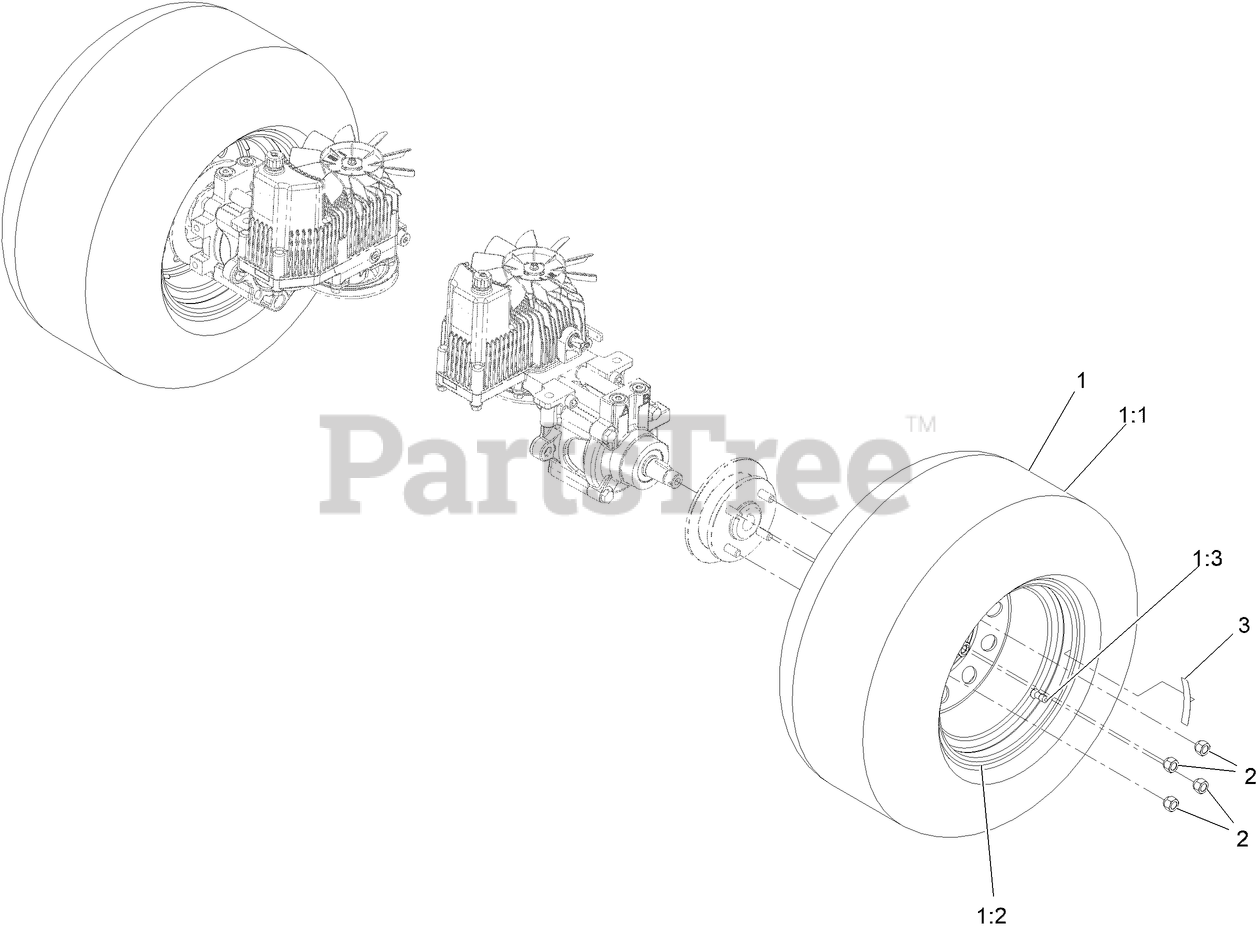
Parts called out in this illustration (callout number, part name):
1	Wheel And Tire ASM Charcoal
1:1	TIRE-24X12-12
1:2	Rim-Charcoal
1:3	Stem-Valve
2	NUT-LUG
3	DECAL-TORQUE, WHEEL HUB LUG
